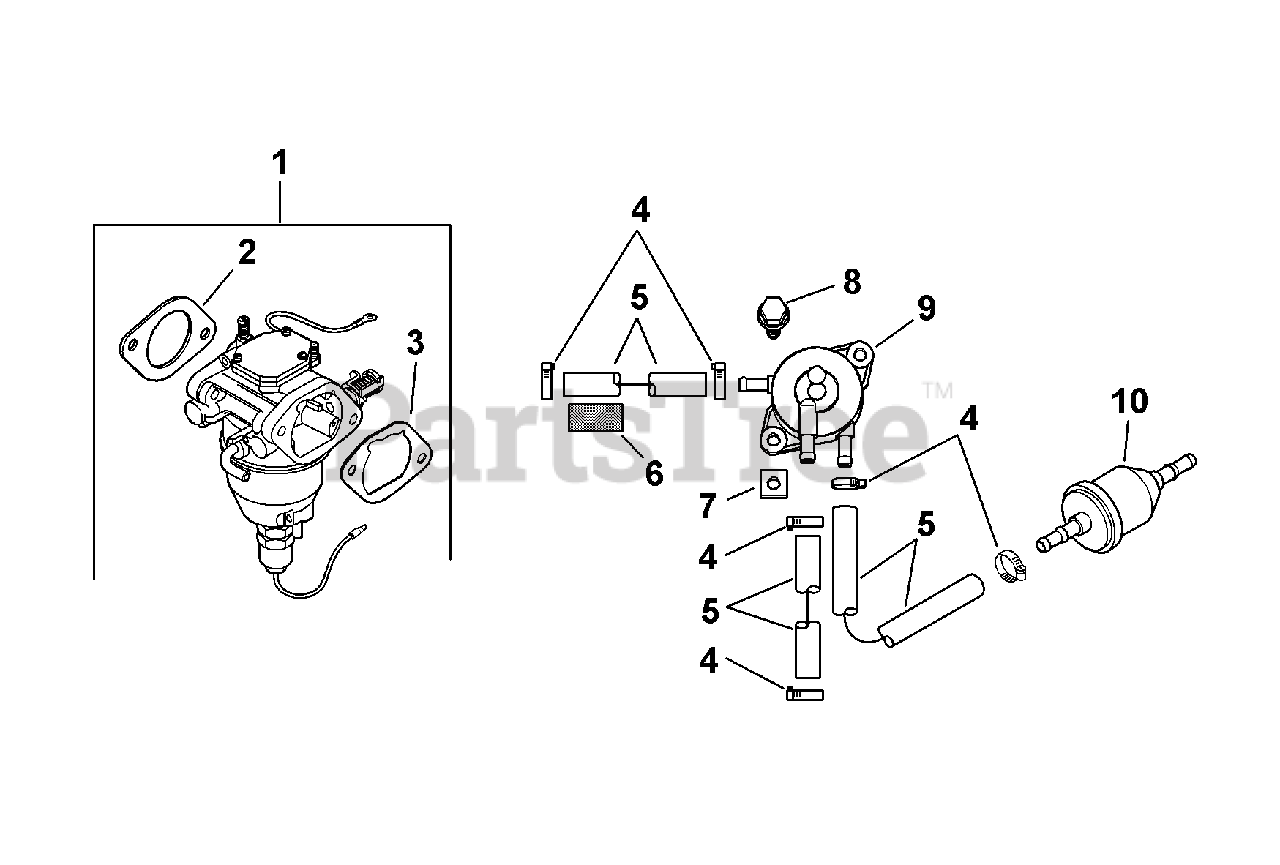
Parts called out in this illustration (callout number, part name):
1	Kit, Carburetor (Includes 2,3)
2	Gasket, Carburetor
3	Gasket, Air Cleaner Base
4	Clamp, Spring Hose 1/2"
5	Line, Fuel (24"-Cut To Length)
6	Insulating Sleeve
7	Nut, Plastic-Black
8	Screw, Tap M6x1.7x18
10	Filter, Fuel
